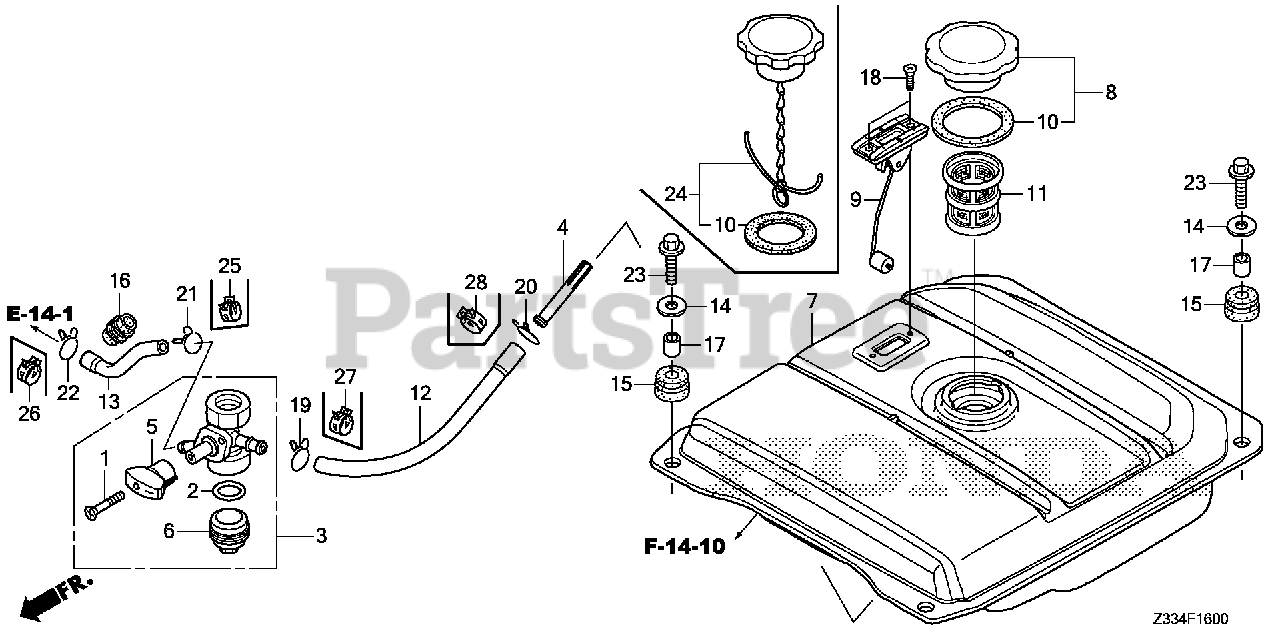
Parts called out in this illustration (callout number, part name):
1	SCREW, OVAL
2	GASKET, FUEL STRAINER CUP
3	PETCOCK ASSY.
4	FILTER, FUEL
5	LEVER, PETCOCK
6	CUP, FUEL STRAINER
7	TANK, FUEL *R280* (POWER RED)
9	METER ASSY., FUEL
10	GASKET, FUEL FILLER CAP
11	FILTER, FUEL
12	TUBE, FUEL TANK (FKM)
13	TUBE, FUEL (FKM)
13	TUBE, FUEL (FKM) (NOT AVAILABLE)
14	WASHER (6MM)
15	CUSHION, TANK RUBBER
16	RUBBER, FUEL (9X15X20)
17	COLLAR, TANK CUSHION
18	SCREW, FLAT (5X10)
23	BOLT, FLANGE (6X22)
24	CAP, FUEL FILLER
25	CLIP, TUBE (D8)
26	CLIP, TUBE (D8.5)
27	CLAMP, TUBE (D10)
28	CLAMP, TUBE (D12)
